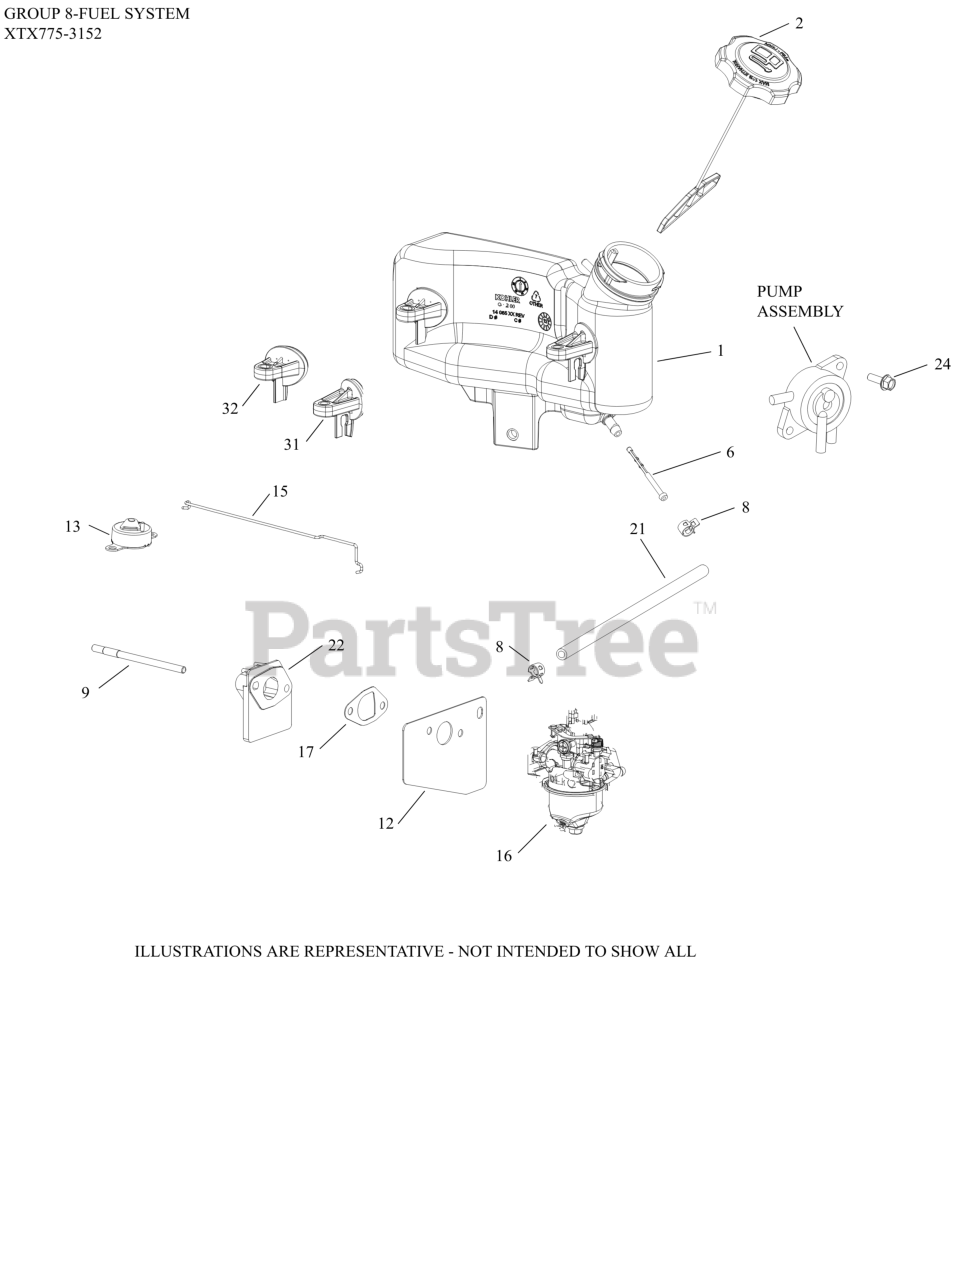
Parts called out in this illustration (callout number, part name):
1	TANK, FUEL
2	FUEL CAP ASSEMBLY
6	FILTER, FUEL IN-NIPPLE
8	CLAMP, HOSE (NON-CALIF)(#1423710S)
9	STUD,M6X1.0X100.2MM
12	KIT, CARBURETOR HEAT SHIELD GASKET
13	ARM ASSEMBLY, AUTO CHOKE
15	LINKAGE, AUTO CHOKE
16	CARBURETOR KIT
17	KIT, INTAKE GASKET
21	HOSE, FUEL LOW-PERMEATION
22	KIT, SPACER
24	SCREW, HEX FLANGE (M6)
31	BRACKET, FUEL TANK
32	BRACKET, FUEL TANK
NI	KIT, HIGH ALTITUDE - USE 14 755 04-S
NI	KIT, CARBURETOR REPAIR (RUIXING)
